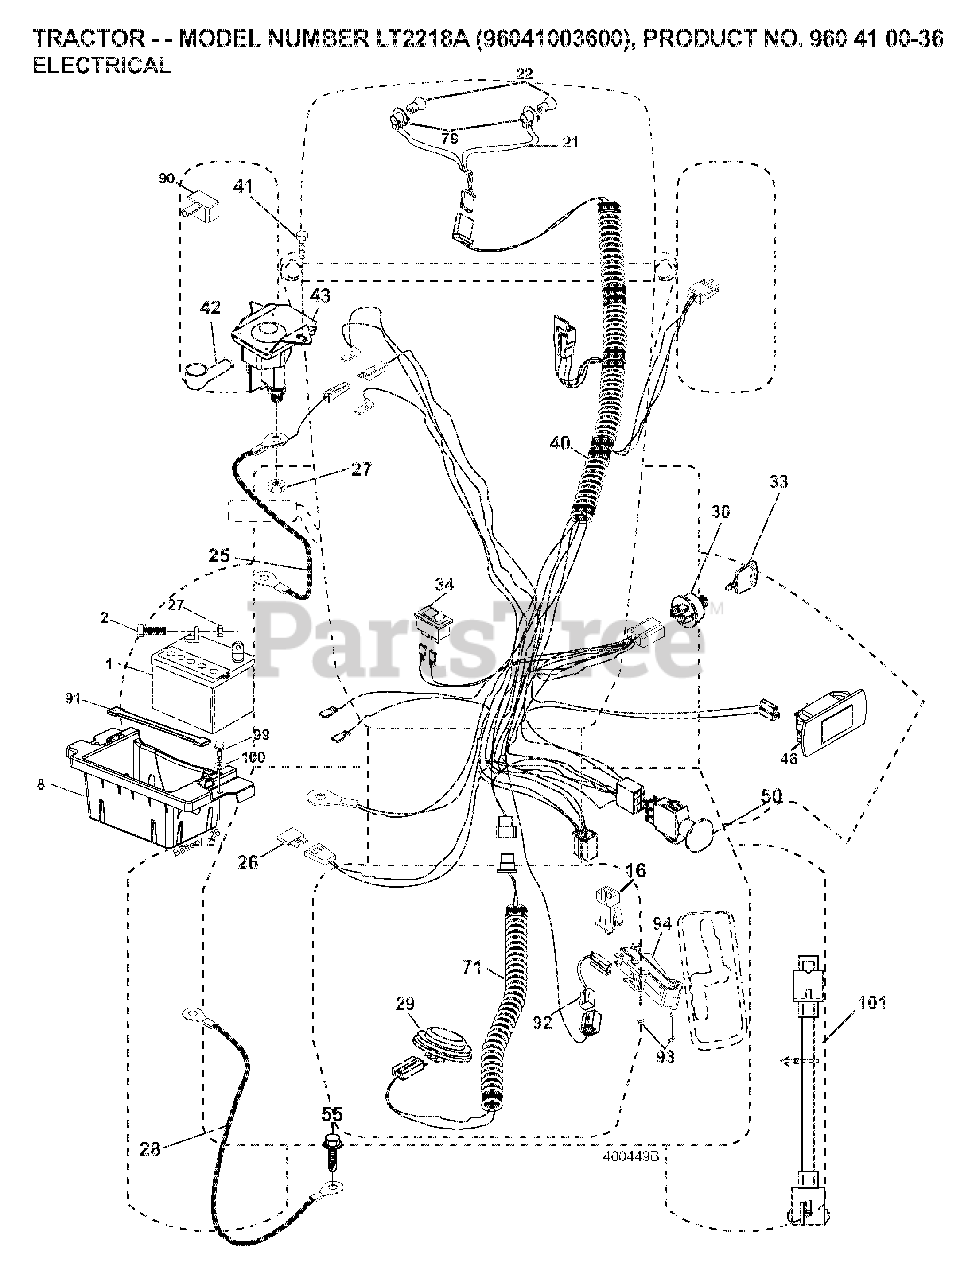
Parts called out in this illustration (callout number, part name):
1	BATTERY 12V .35 AMP
8	BOX.BATTERY.MNT.REAR.L
16	SWITCH INTERLOOK PUSH-IN
21	HARNESS.W/LIGHT SOCKET
22	LIGHTBULB
25	CABLE.START.RED.17.5".
26	FUSE 20AMP
27	NUT
28	CABLE.BLACK.18"REAR.BA
29	SWITCH.SEAT.DELTA.OPC.
30	SWITCH.IGN.DELTA.W.LGH.ROS
33	KEY MLD GEN DELTA
34	SWITCH LT
40	HARNESS.IGN.DASH.HUQ/P
41	SCREW
42	TERMINAL COVER
43	SOLENOID.W/BRASS.PLUNG
46	GUAGE.SRVCMNDR.HRMTR.
50	PTO SWITCH
55	SCREW 5/16"
71	HARNESS.IGN.CHASS.TEX.REAR.BAT
79	BULB HOLDER ASM.
90	COVER, TERMINAL BATTERY
92	HARNESS.PIGTAIL.CONSLE
93	SCREW.PLASTITE
94	MODULE.REVERSE.ROS
101	PIGTAIL.MATNLK.NEW.HAR
